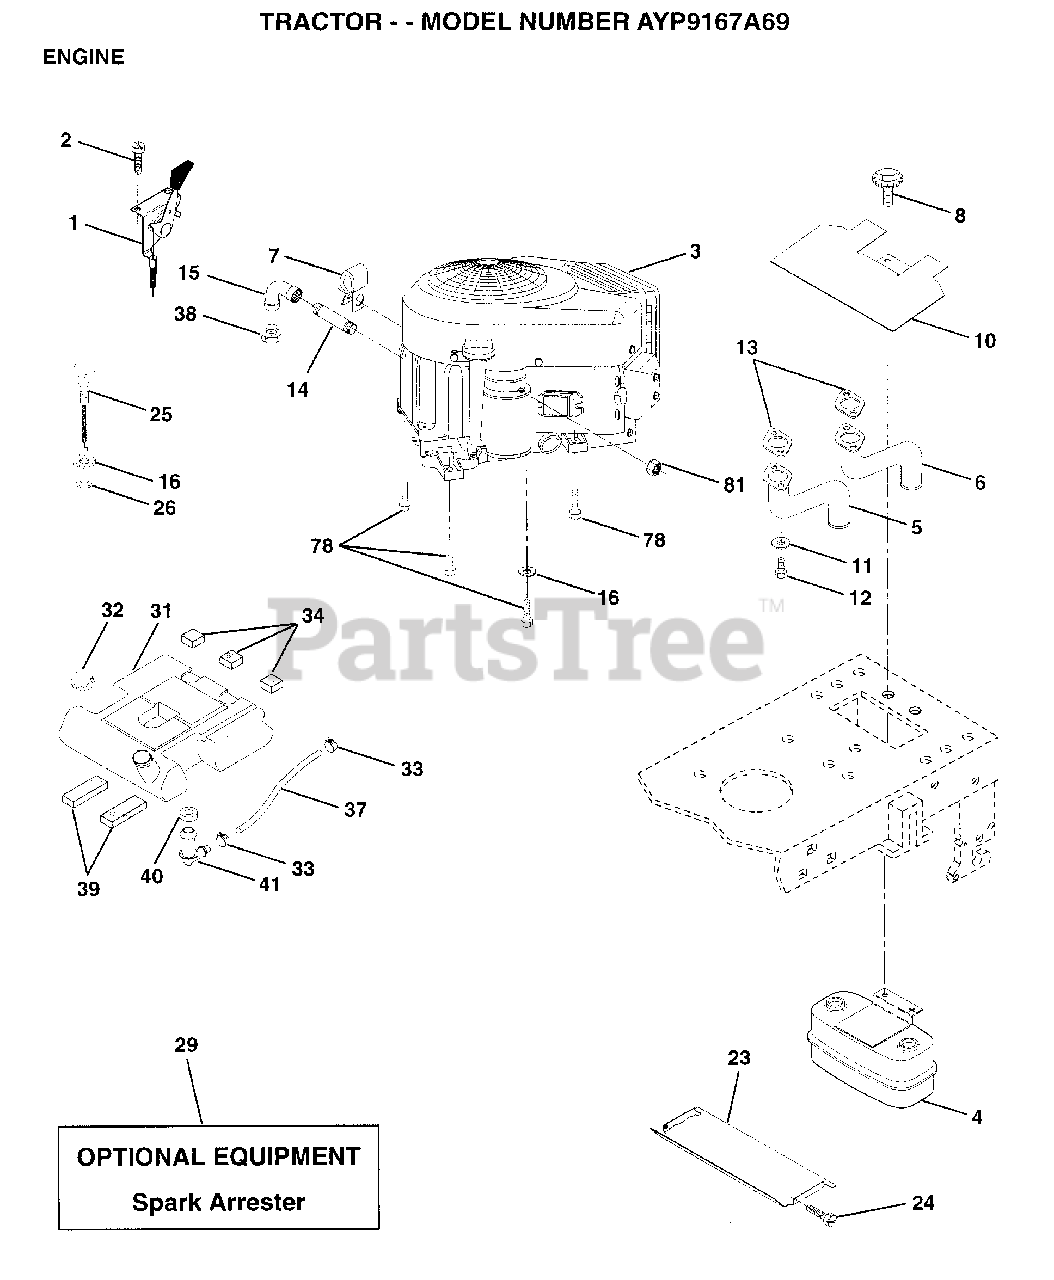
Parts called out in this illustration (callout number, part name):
1	CONTROL THROT. LH
2	SCREW LT
4	MUFFLER.TW.LOTONE
5	TUBE ASSY EXH LH
6	TUBE ASSY EXH RH
7	CLAMP.TUBE.DBL.EN
8	BOLT.5/16-18.UNC
10	SHIELD.HEAT.
14	PIPE NIPPLE LT
15	ELBOW
16	LOCKWASHER
23	HEAT SHIELD
24	SCREW
25	CONTROL.CHOKE.37
26	"NUT,KEPS 3/8-24IM"
32	CAP ASM FUEL
33	HOSE CLAMP
34	PAD-SPACER LT
37	FUEL LINE T
39	PAD IDLER TI
40	BUSHING OUTLET T
78	SCREW
81	NUT
